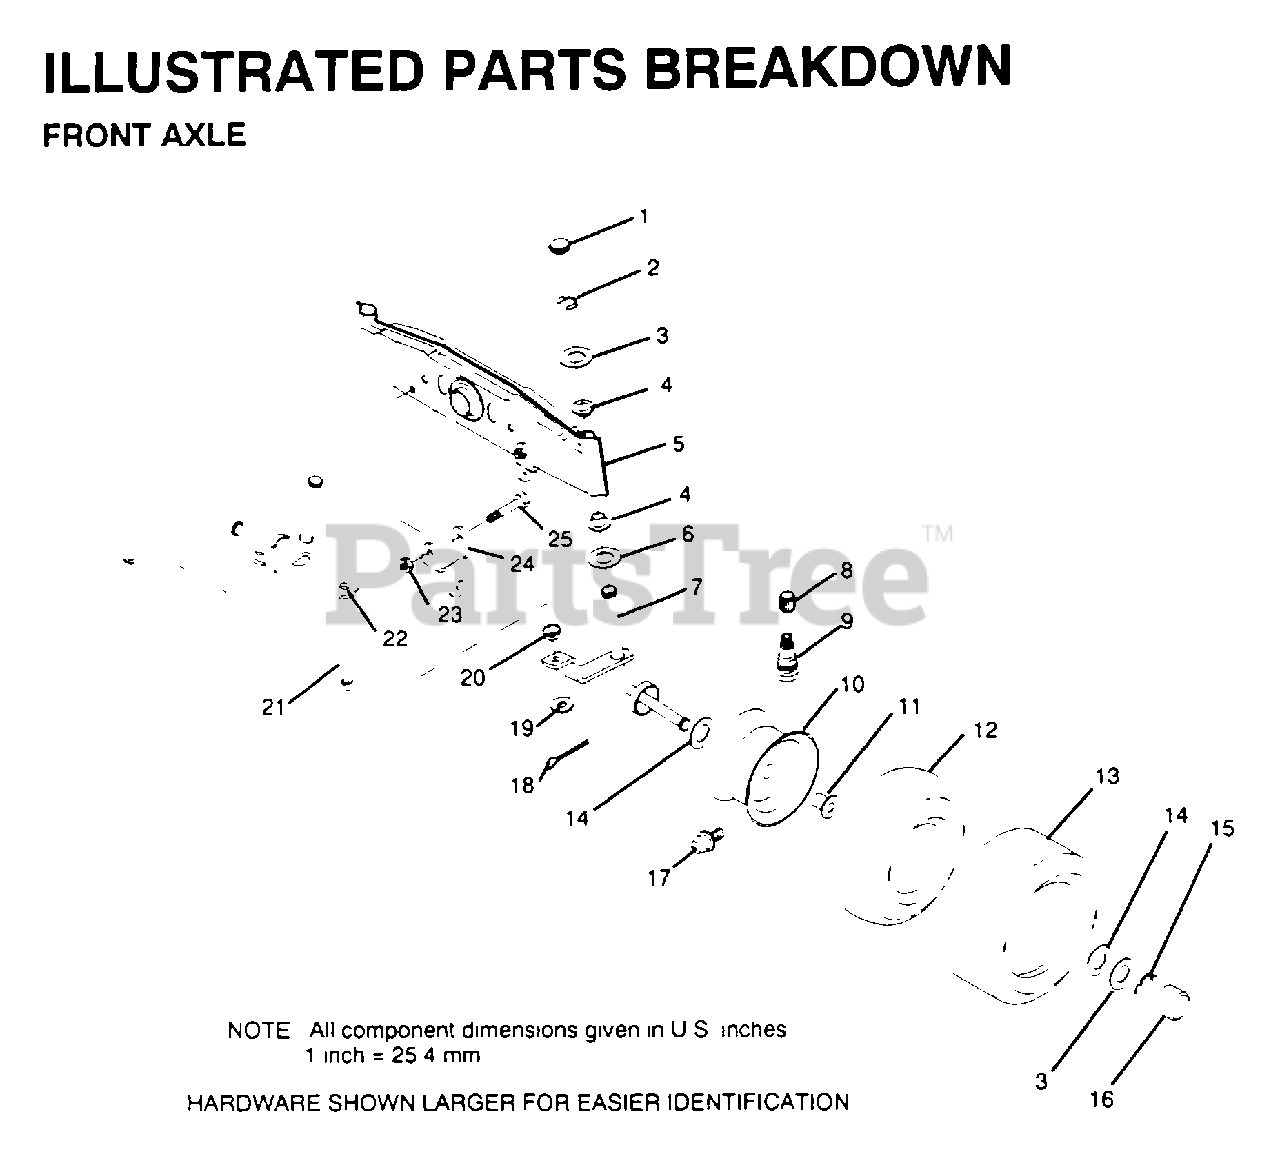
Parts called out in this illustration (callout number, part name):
1	CAP
2	RING
3	WASHER
4	NYLINER
5	AXLE FRONT
6	WASHER .T
7	SPINDLE RH
8	VALVE CAP
9	VALVE STEM LT
11	"FLANGE, BEARING"
12	TUBE.5.3/4.5/6
14	WASHER
15	RING
16	HUB CAP
17	FITTING LT
18	COTTER PIN
19	WASHER
20	BUSHING.DRAGLINK
21	ROD TIE
22	SPINDLE LH
24	"BRKT,FRONT STAB"
25	BOLT
